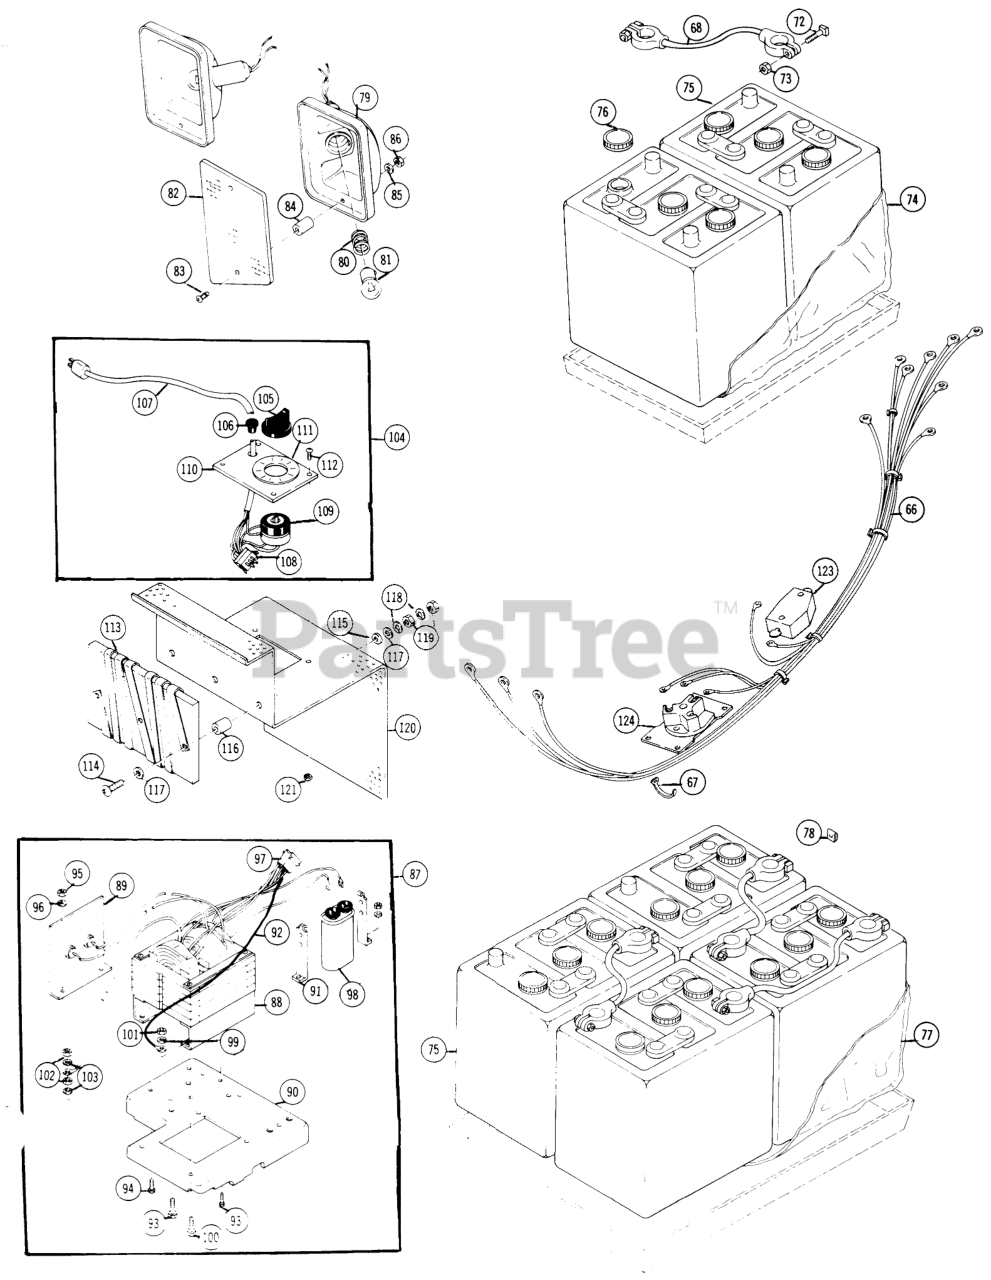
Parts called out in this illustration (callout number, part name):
11-06	Nut, Hex 5/16-18
11-11	Cable Tie
11-66	Grill Harness
11-67	Cable Tie
11-68	Battery Cable Assembly
11-69	Battery Post Clamp (+)
11-70	Battery Post Clamp (-)
11-71	Wire, #6 AWG
11-72	Bolt, Sq. Hd. 5/16-18
11-73	Nut, Hex 5/16-18
11-74	Poly Bag Liner, Front
11-75	Battery, Heavy-Duty 6 Volt (Deep Discharge)
11-76	Battery Cap
11-77	Poly Bag Liner, Rear
11-78	Clip, Wire
11-79	Reflector and Light Socket
11-80	Spring
11-81	Bulb, Head Light
11-82	Lens, Headlight
11-83	Screw, Pan Hd. #6-32 x 1
11-84	Spacer
11-85	Lockwasher #6
11-86	Nut, Hex #6-32
11-87	Battery Charger (Complete)
11-88	Transformer
11-89	Heat Sink Assembly
11-91	Bracket
11-92	Wire (#47)
11-93	Screw, Hex Machine #10-32 x 7/8
11-94	Screw, Hex Machine
11-95	Nut, Hex #8-32
11-96	Lockwasher-#8
11-97	Pin Housing
11-98	Capacitor
11-99	Lockwasher 1/4
11-100	Bolt, Hex 1/4-20 x 1
11-101	Nut, 1/4-20
11-102	Nut #10-32
11-103	Lockwasher #10
11-104	Timer Assembly
11-105	Timer Knob
11-106	Bushing, Charger Cord
11-107	Charger Cord
11-108	Socket Housing
11-109	Timer
11-110	Mounting Plate
11-111	Timer Dial
11-112	Screw, Machine #10-24 x 3/4 Phillips Hd.
11-113	Power Resistor Assembly
11-114	Screw, Phillips Pan Hd. 1/4-20 x 2
11-115	Washer, Fiber
11-116	Spacer
11-117	Washer 1/4
11-118	Lockwasher 1/4
11-119	Nut, 1/4-20
11-120	Cover
11-121	Speed Nut
11-122	Screw, Thrd. Rolling #8-32 x 1/2 Dull Black
11-123	Accessory Outlet
11-124	PTO Outlet
11-125	Brake Switch
11-126	Mach. Screw #10-32 x 3/4
11-127	Lockwasher
11-128	Jumper Wire #52
